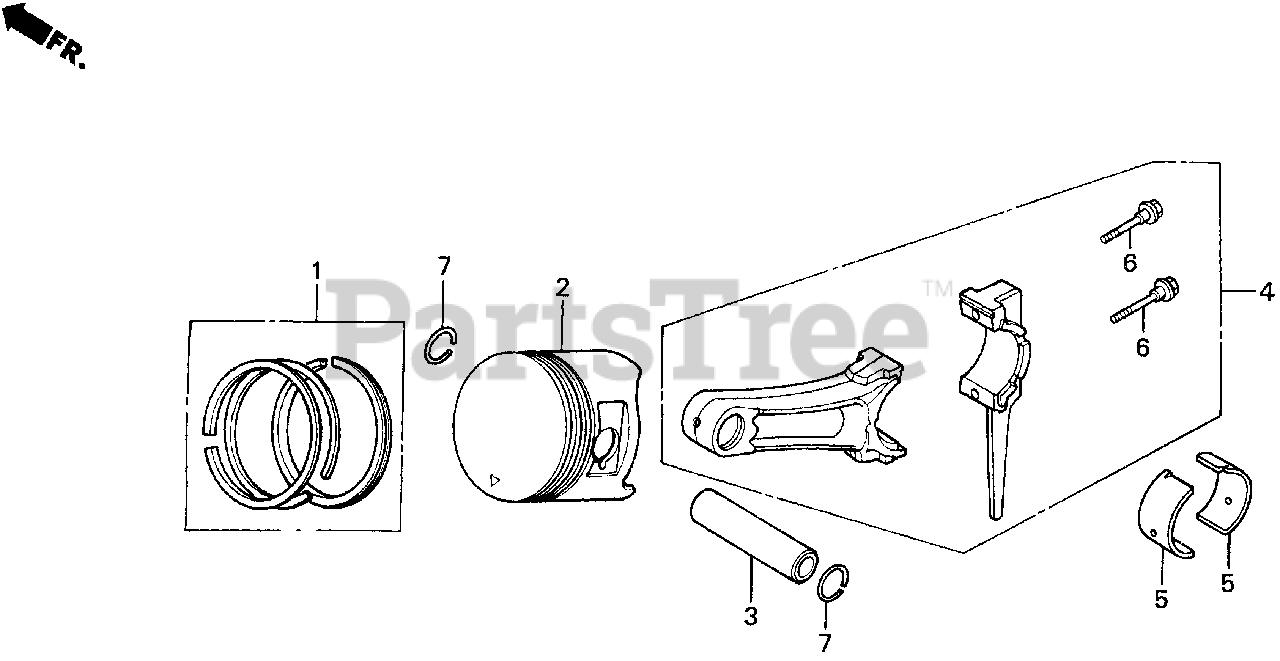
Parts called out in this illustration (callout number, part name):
1	RING SET, PISTON (STD) (NIPPON)
1	RING SET, PISTON (OS 0.25)
1	RING SET, PISTON (OS 0.50)
2	PISTON (STD)
2	PISTON (OS 0.25)
2	PISTON (OS 0.50)
3	PIN, PISTON
4	ROD ASSY., CONNECTING
5	BEARING A, CONNECTING ROD (BLUE)
5	BEARING B, CONNECTING ROD (BLACK)
5	BEARING C, CONNECTING ROD (BROWN)
5	BEARING D, CONNECTING ROD (GREEN)
6	BOLT, CONNECTING ROD
7	CLIP, PISTON PIN (20MM)
